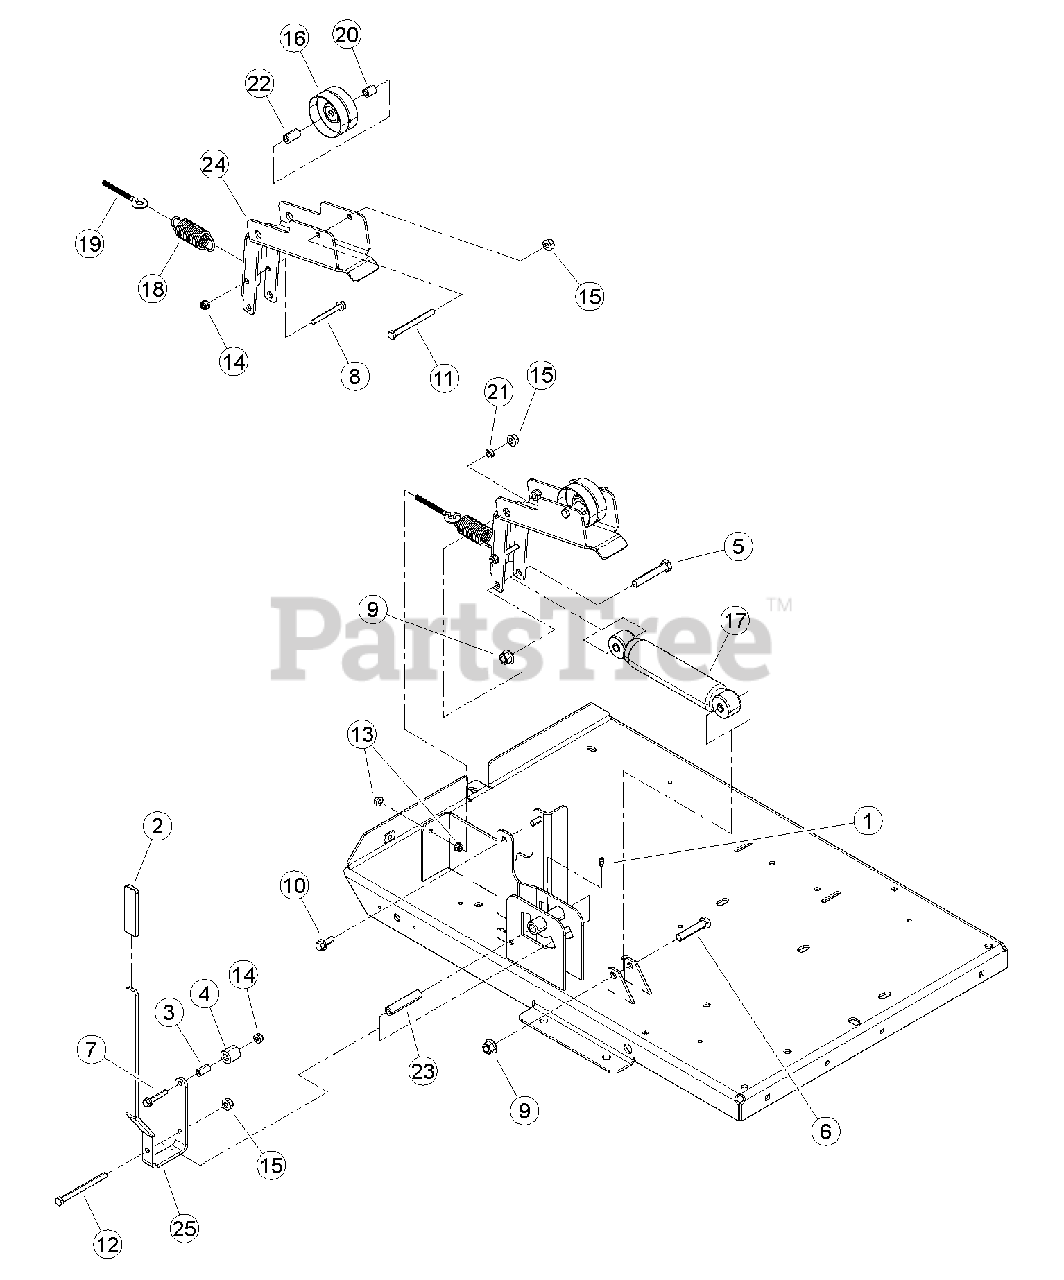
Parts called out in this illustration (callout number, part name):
1	FITTING, 1/4 SELF-TAP GREASE
2	GRIP, CLUTCH HANDLE
3	SPACER, 0.5 X 1.00
4	ROLLER, 0.5 X 1.00 X 1.00 NYLON
5	BOLT, 1/2 X 3 GR5 HEX HD ZP
6	BOLT, 1/2 X 2-1/2 GR5 HEX CAP ZP
7	BOLT, 5/16 X 1-3/4 FLANGE NC
8	BOLT, 5/16 X 2-3/4 FLANGE NC
9	NUT, 1/2-13 NYLOCK FLANGE
10	BOLT, 3/8 X 1 FLANGE NC
11	BOLT, 3/8 X 4" HHCS GR5 NC ZP
12	BOLT, 3/8 X 4-1/2" HHCS GR5 NC ZP
13	NUT, 5/16-18 SERRATED FLANGE NC
14	NUT, 5/16-18 NYLOCK FLANGE
15	NUT, 3/8-16 NYLOCK FLANGE
16	PULLEY, 3-1/4 FLAT IDLER
17	ABSORBER, IDLER SHOCK
18	SPRING, 1.25 OD X 3.50 LG X .148 WD
19	BOLT, 5/16 X 3-5/8" EYE
20	SPACER, 3/4" LONG IDLER TUBE
21	SPACER, IDLER PIVOT
22	SPACER, IDLER
23	SPACER, .63 X 3.060
24	WELDMENT, IDLER BRACKET
25	LEVER, CHIPPER ENGAGEMENT
